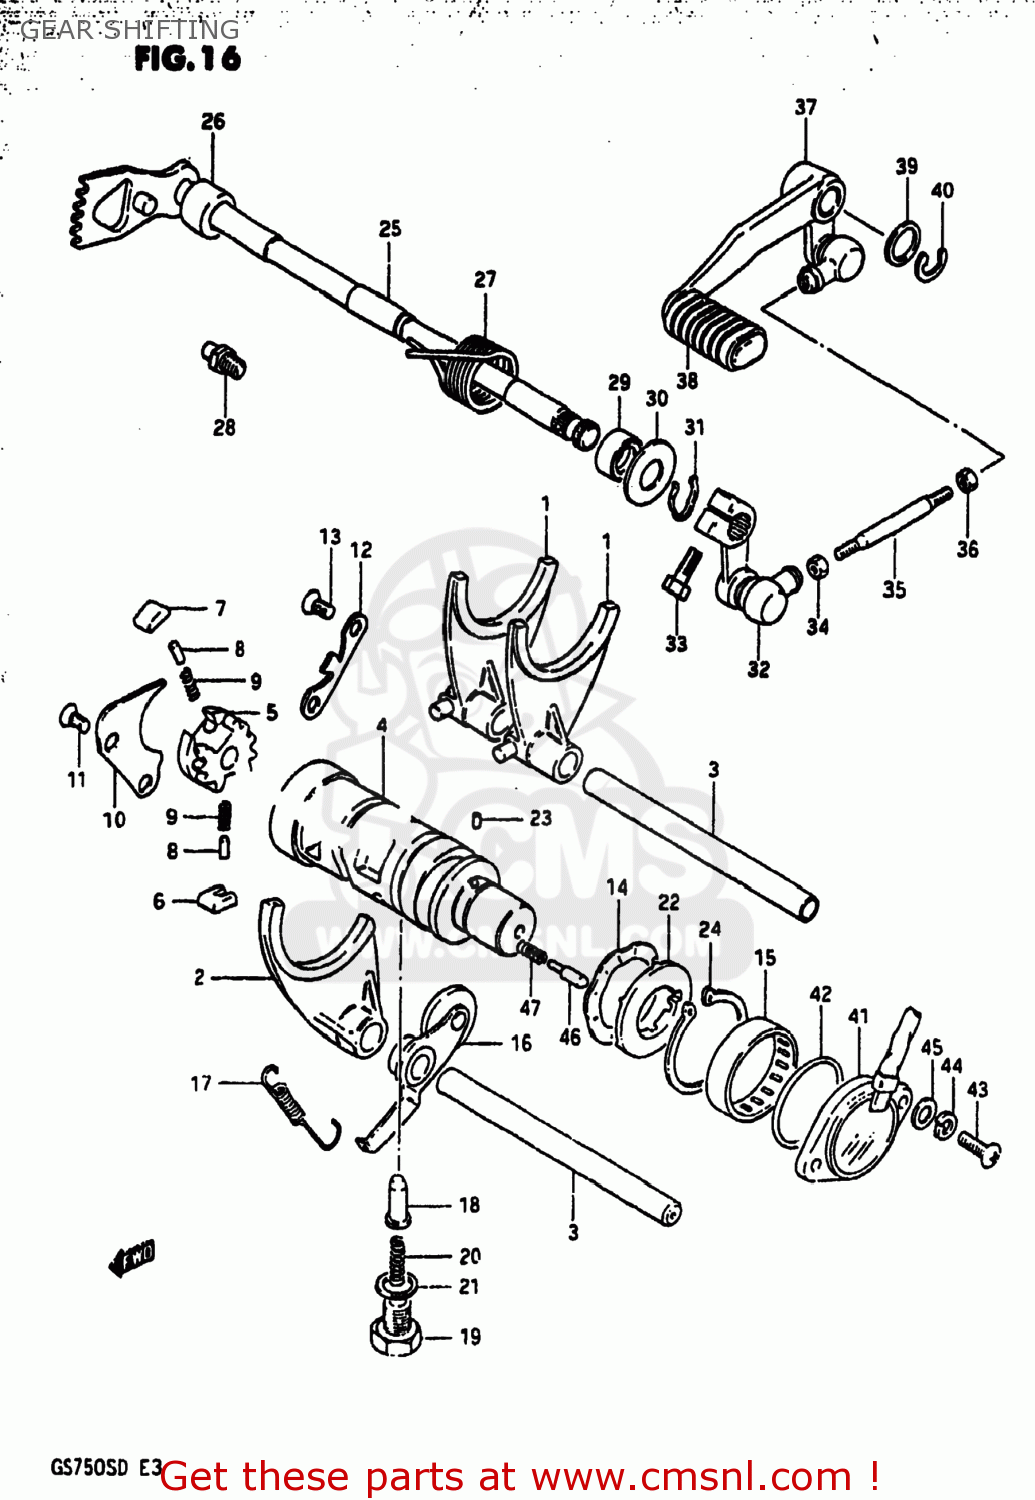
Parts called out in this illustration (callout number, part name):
1	FORK,GEAR SHIFT NO.1
2	FORK,GEAR SHIFT NO.3
3	SHAFT,GEAR SHIFT FORK
4	CAM,GEAR SHIFT
5	RETAINER,GEAR SHIFT CAM
6	PAWL,GEAR SHIFT NO.1
7	PAWL,GEAR SHIFT NO.2
8	PIN(5X8)
9	SPRING
10	LIFTER,GEAR SHIFT PAWL
11	SCREW
12	GUIDE,GEAR SHIFT CAM
13	SCREW
14	WASHER(40X45X1)
15	BEARING(25X32X12)
16	STOPPER,GEAR SHIFTING
17	SPRING
18	STOPPER,GEAR SHIFT CAM NO.2
19	HOLDER,GEAR SHIFT CAM STOP SPR
20	SPRING
21	GASKET(14X19.2X2) (NAS)
22	PLATE,GEAR SHIFT CAM STOPPER
23	PIN 4X6
24	CIRCLIP,25MM
25	SHAFT,GEAR SHIFT
26	SPACER(12X20X15.3)
27	SPRING
28	STOPPER,GEAR SHIFT CAM
29	OIL SEAL
30	WASHER (12.5X27X1.6)
31	SPRING,RETAINER
32	ARM,GEAR SHIFT
33	BOLT
34	NUT
35	ROD,GEAR SHIFT LINK
36	NUT
37	LEVER ASSEMBLY,GEAR SHIFTING
38	RUBBER,PEDAL
39	WASHER(12.5X20X1)
40	CIRCLIP
41	TERMINAL BASE,NEUTRAL SWITCH
42	O-RING (D:2.4 ID:26.2)
43	SCREW 5X20
44	LOCK WASHER
45	WASHER
46	PIN(5X15.5)
47	SPRING
